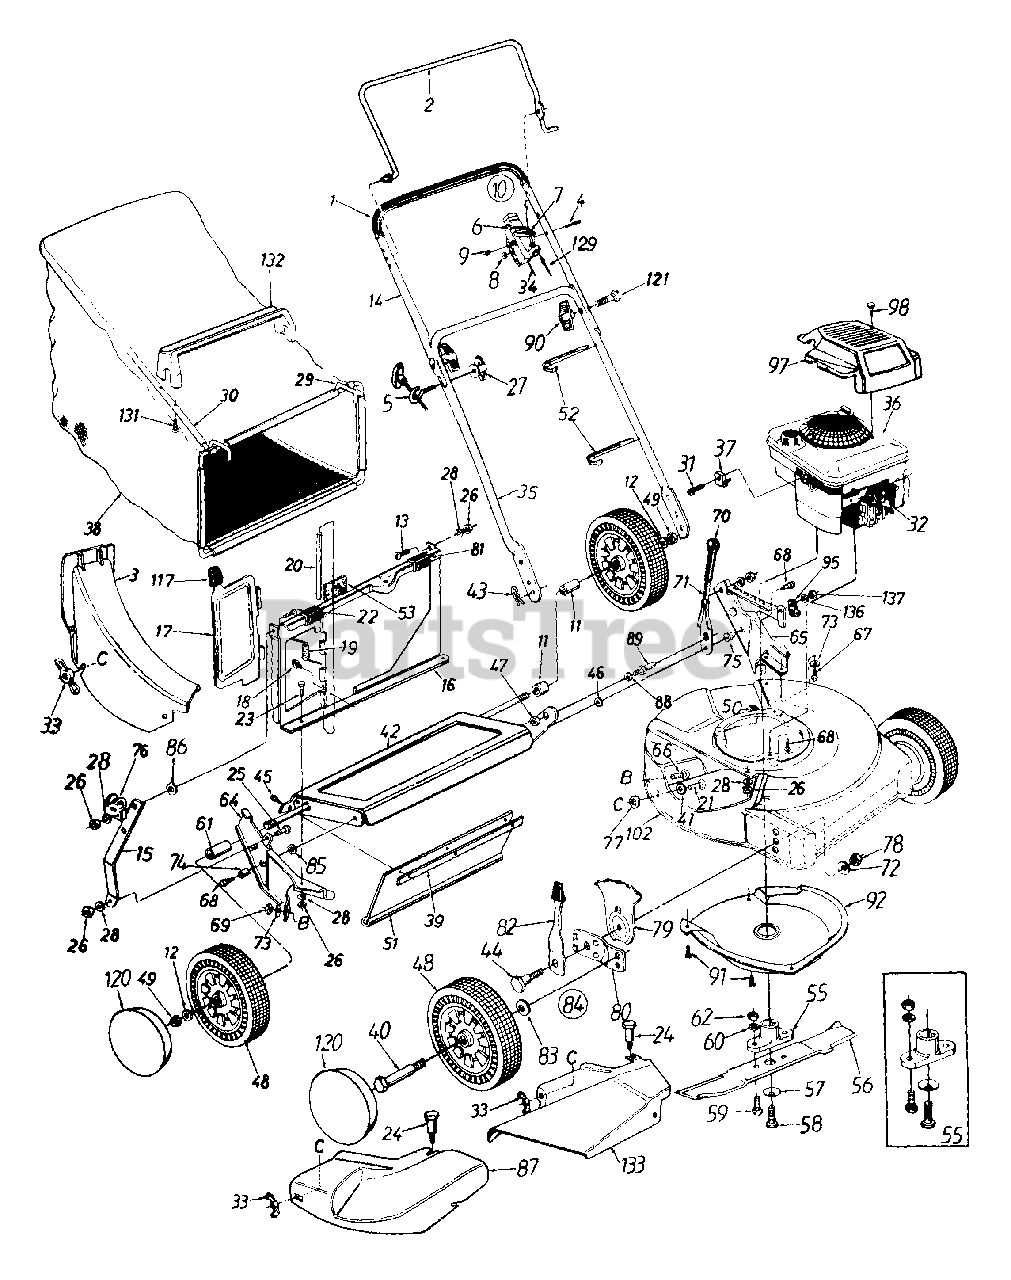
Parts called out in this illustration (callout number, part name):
1	Grip
2	Control Handle Ass'y.
3	Top Discharge Chute Ass'y.
4	Oval C-Sunk Scr.
5	Rope Guide
6	Throttle Body
7	Throttle Lever
8	Spr. Wash..66" I.D.
9	Hex L-Nut 1/4-20 Thd.
10	Throttle Box Comp.
11	Spacer .526" I.D. x .690" O.D. x .640" Lg.
12	Fl-Wash..510" I.D. x .75"
13	Truss Mach. Scr. 1/4-20 x.62"
14	Upper handle
19	Torsion Spring
20	Pivot Pin
21	Carriage Bolt 1/4-20 x .62"
22	Truss Mach. Scr. 1/4-20 x .75"
23	Hex Bolt 1/4-20 x .50" Lg.
24	Shoulder Bolt .312" Dia. x .18" Lg.
25	Hex Bolt 1/4-20 x .62" Lg.
26	Hex Nut 1/4-20 Thd.
27	Wing Nut 1/4-20 Thd.
28	L-Wash. 1/4" I.D.
30	Upper Bag Support
31	Hex Self-Tap Scr. #10-32 x .62"
32	Spark Plug Insulator
33	Wing Nut w/Washer
34	Throttle Control Wire 61"
36	Engine
37	Cable Clamp
38	21" Top Discharge Grass Bag
39	Retaining Strip
40	Shld. Bolt .498" Dia. x 1.45"
41	Fl-Wash..344" I.D. x .62"
44	Shld. Bolt .5" Dia. x .357"
45	Hex AB-Tap Scr. 1/4 x .62"
46	Fl-Wash..38" I.D. x 1.0"
47	Hex Jam Nut 3/8-24 Thd.
48	Wheel Ass'y. Comp.
49	Hex L-Nut 1/2-20 Thd.
51	Rear Flap 3.75" x 17.30" Lg.
52	Cable Tie
53	Foam Strip 1" Lg.
55	Blade Adapter Kit
56	21" Mulching Blade
57	Bell-Wash..47" I.D.
58	Hex Bolt 7/16-20 x 1.5" Lg.
59	Hex Bolt 3/8-24 x 1" Lg.
60	L-Wash. 3/8" I.D.
61	Sleeve .526" I.D. x .69"
62	Hex Nut 3/8-24 Thd.
64	R.H. Handle Wheel Brkt. Ass'y.
65	L.H. Handle Wheel Brkt. Ass'y.
66	Carriage Bolt 5/16-18 x .62"
67	Hex Wash. Hd. B-Tap Scr. 5/16-18
69	Hex Nut 5/16-18 Thd.
71	Height Adj. Lever
72	Bell-Wash..39" I.D. x 1.38" O.D.
73	Bell-Wash. 5/16" I.D.
74	Spacer .383" I.D. x .503" O.D.
75	Shld. Spacer .500" Dia.
76	Rope Guide
77	Bolt Retainer 1/4 x .50" O.D.
78	Hex Nut 3/8-16 Thd.
79	Height Adj. Plate
80	Pivot Bar
81	Panel Clip
82	Spring Lever Ass'y. w/Knob
83	Bell-Wash..38" I.D. x .88" O.D.
84	Height Adj. Ass'y. Comp.- R.H.
85	Fl-Wash. 3/8" I.D. x 1" O.D.
86	Fl-Wash..285" I.D. x 1.25" O.D.
87	Mulching Plug
88	L-Wash. 3/8" I.D.
89	Shld. Pin 3/8-24 x 1.43" Lg.
90	Hand Knob
91	Hex Wash. Hd. Tap Scr. 1/4 x .5" Lg.
97	Engine Shroud
98	Screw #10 x 1.25" Lg.
120	Hub Cap
121	Curved Hd. Bolt 5/16-18 x 2" Lg.
129	Control Cable - 44" Lg.
131	Hex AB-Tap Scr. #12 x 1.0"
132	Bag Handle
133	Side Chute Deflector Ass'y.
136	Fl-Wash..385" I.D. x.87" O.D.
137	Hex Patch L-Nut 3/8-24 Thd.
